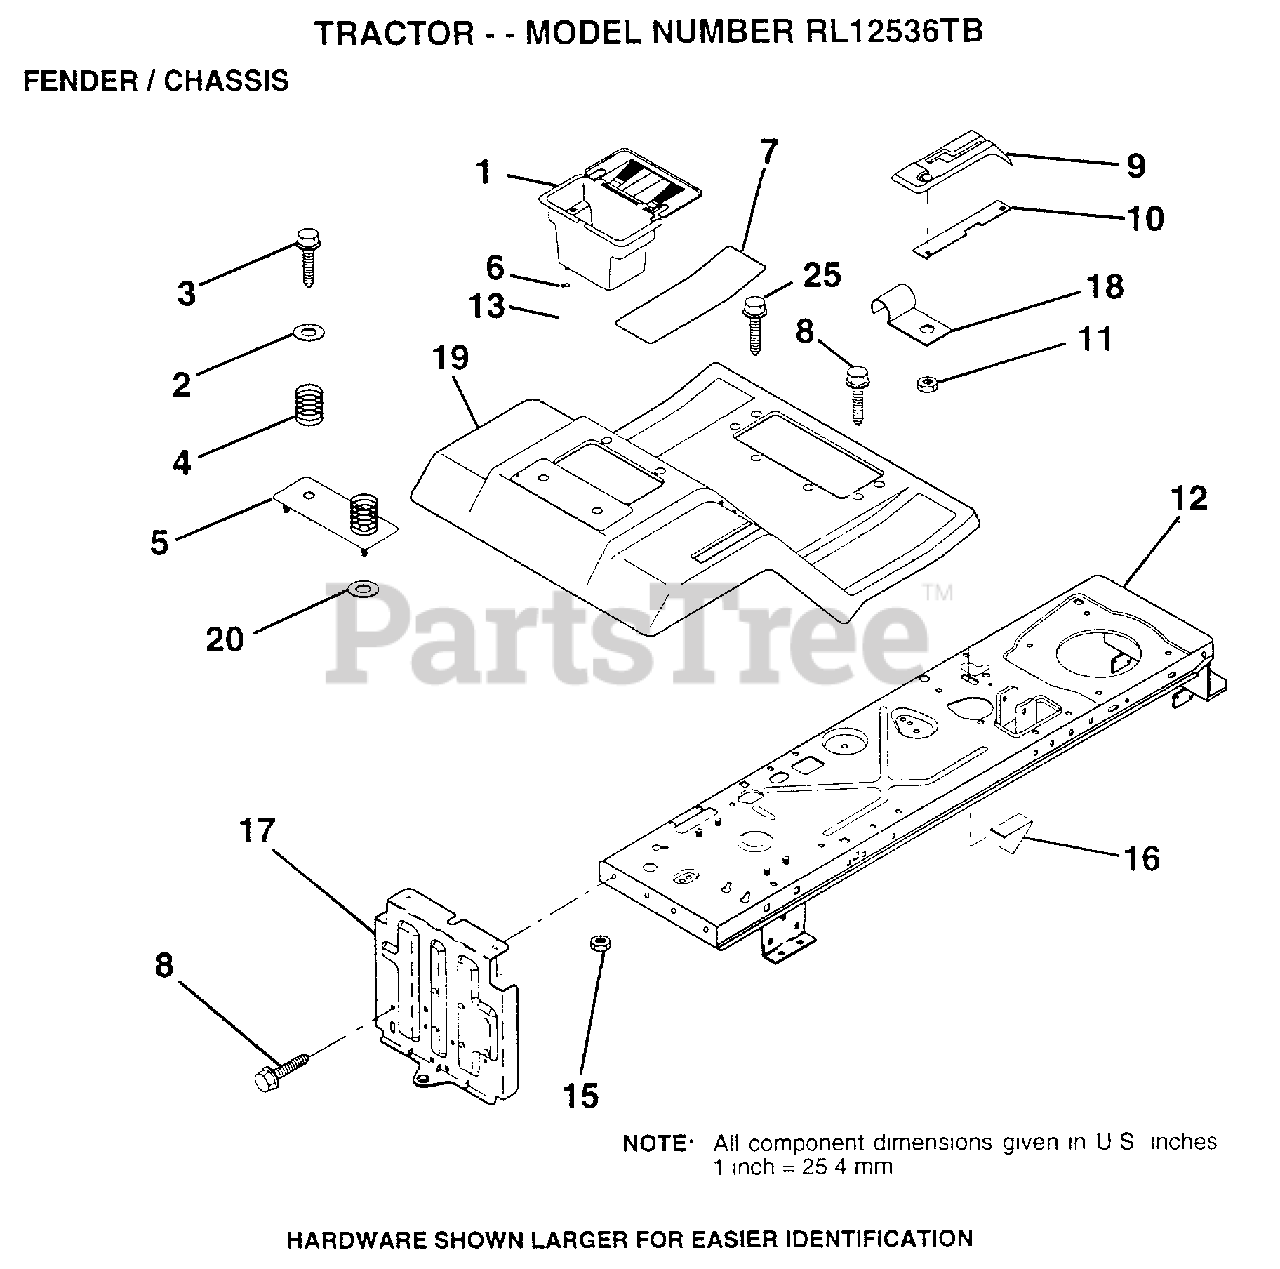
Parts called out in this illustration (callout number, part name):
2	WASHER
3	SCREW
4	SPRING COMPRESSIO
5	BTRY FENDER PLATE
6	HOSE CLAMP T
7	PAD FOOTREST
8	SCREW
9	CONSOLE SHFT 5SP
10	PLATE LOCK SHIFT
11	NUT
12	CHASSIS.WELD.ASM.
13	TUBE T
15	NUT HXKEP 1/4X20
17	DRAWBAR ASM LR
18	"CLIP,INSULATOR"
19	FENDER/FOOT MS505
25	SCREW
